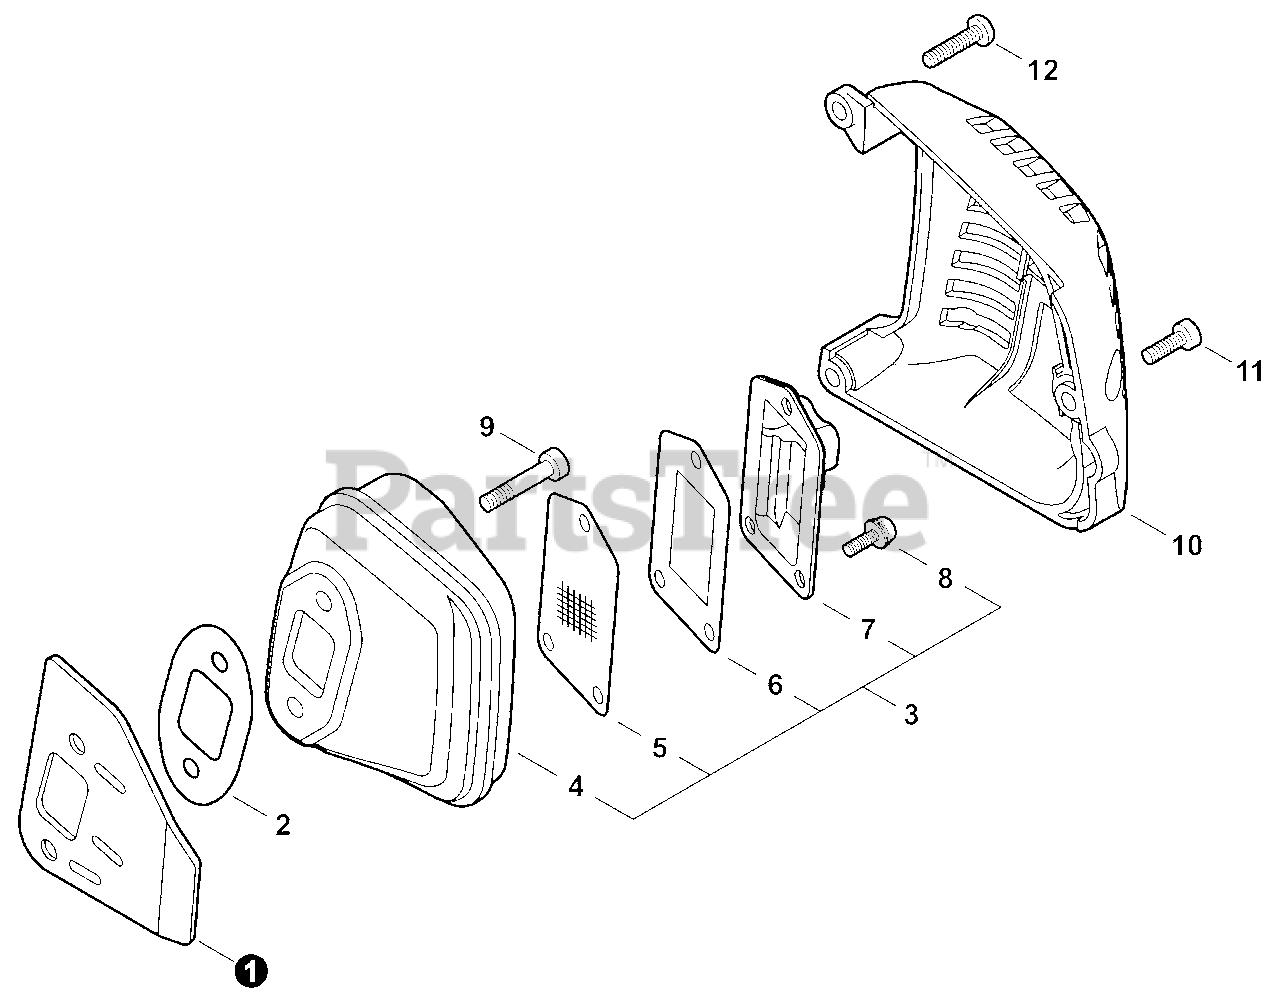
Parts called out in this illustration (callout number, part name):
1	HEAT SHIELD, EXHAUST
2	GASKET, EXHAUST
3	MUFFLER ASSY
4	MUFFLER
5	SCREEN, SPARK ARRESTER
6	GASKET, EXHAUST
7	GUIDE, EXHAUST
8	SCREW 4×10
9	BOLT, TORX 5×16
10	COVER, MUFFLER
11	BOLT, TORX 5×16
12	BOLT, TORX 5×20
